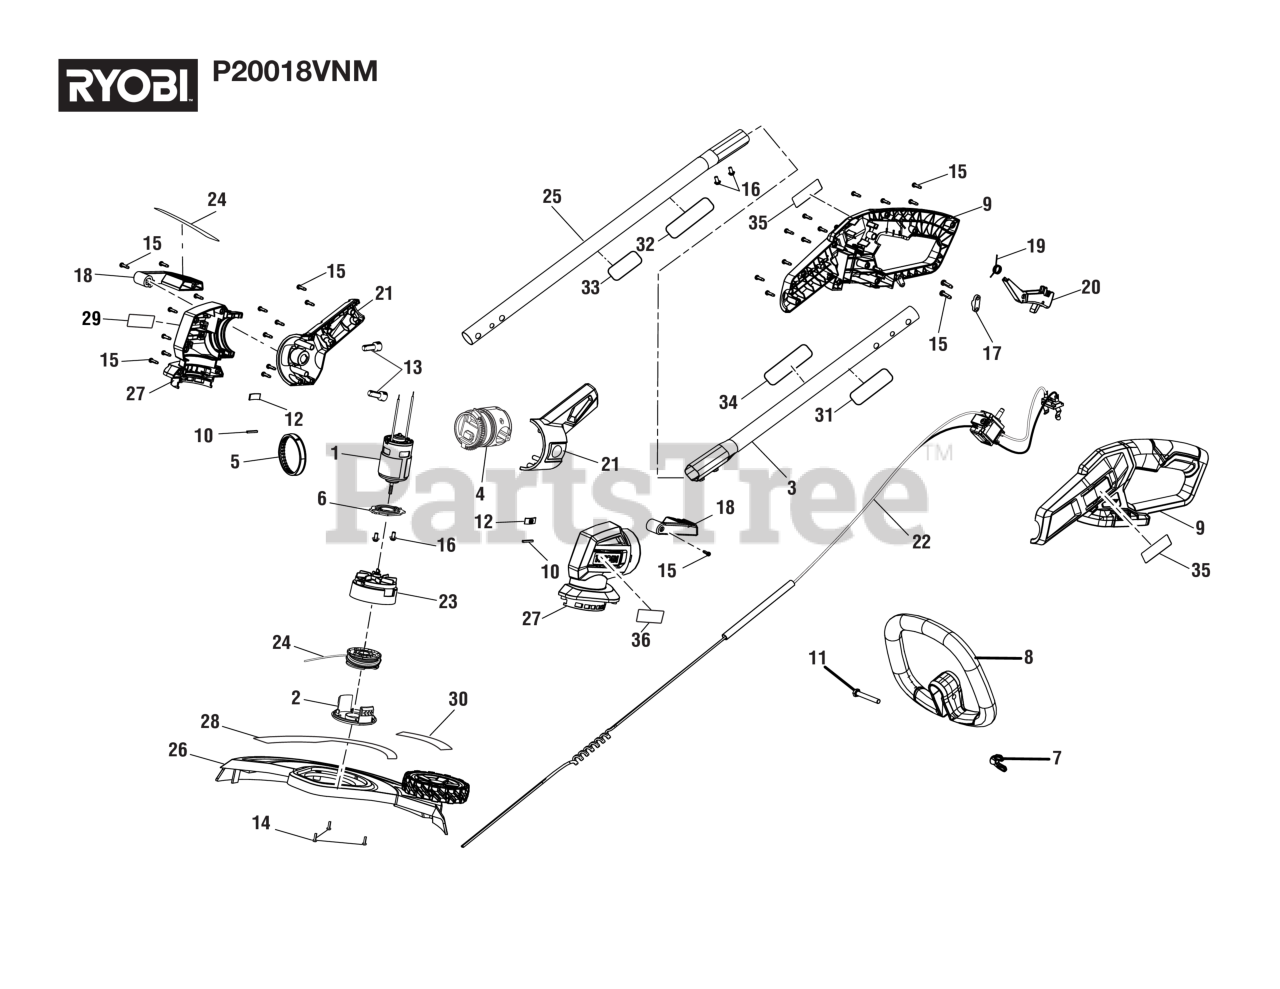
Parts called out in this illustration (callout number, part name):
2	Spool Cover
3	Upper Tube Assembly
4	Pivot Assembly
5	Plastic Ring
6	Motor Mounting Plate
7	Wing Nut (1/4-20, Plastic)
8	Front Handle
9	Handle Housing Assembly
10	Rubber Plate (Motor Plate)
11	Bolt (1/4-20 x 45 mm, Cap Hex Hd.)
12	Rubber Plate (Motor)
13	Wire Connector (Closed End)
14	Screw (M4 x 12 mm, Pan Hd.)
15	Screw (M4 x 14 mm, T15 Torx Pan Hd.))
16	Screw w/Lock Washer (M5 x 8 mm, Pan Hd.)
17	Cord Clamp
18	Adjustment Pedal Assembly
19	Trigger Spring
20	Trigger Assembly
21	Lower Housing Assembly
22	Switch and Contact Plate Assembly
23	Spool Base & Slider Assembly
24	Spool With Line Assembly
25	Lower Tube Assembly
26	Guard Assembly
27	Motor Housing Assembly
28	Autofeed Guard Label
29	Logo Label
30	Adjustable Cutting Width Label
31	Warning Label (French/Spanish)
32	Data Label
34	Warning Icon Label
35	Logo Label
